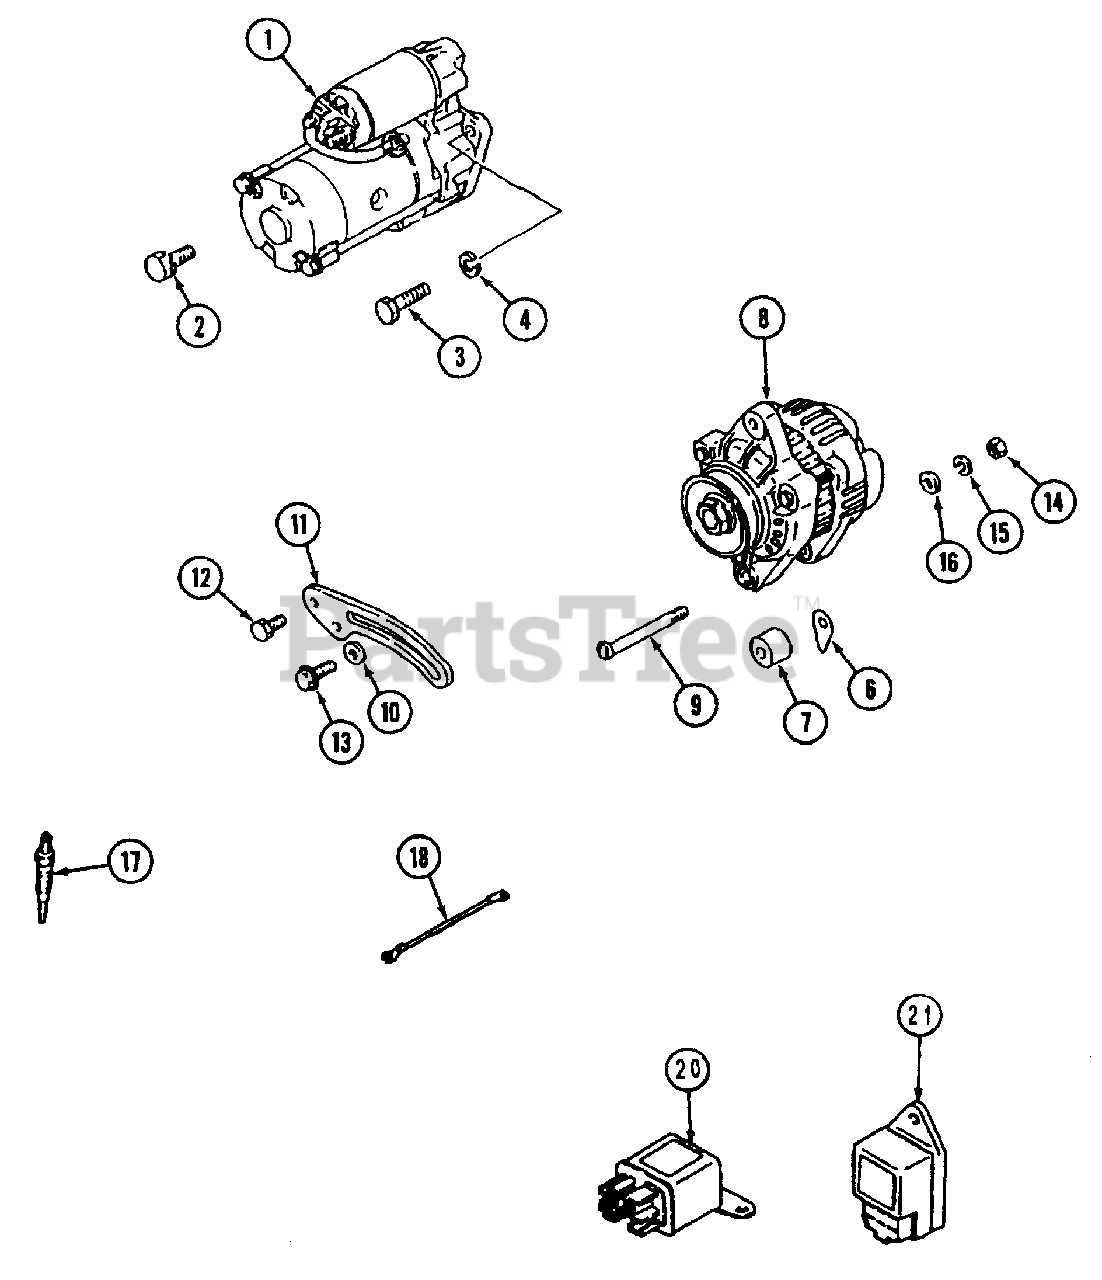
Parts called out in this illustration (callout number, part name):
1	Starter Ass'y.
2	Bolt, W/Washer
3	Bolt, Starter
4	Washer, Lock
8	Alternator Ass'y.
9	Bolt, Special
10	Washer, Plain
11	Blace, Generator
12	Bolt, W/Washer
13	Bolt, Flange
15	Washer, Spring
16	Washer, Plain
17	Plug, Glow
18	Wire, Glow Plug Lead
20	Relay, Glow
21	Timer, Glow
